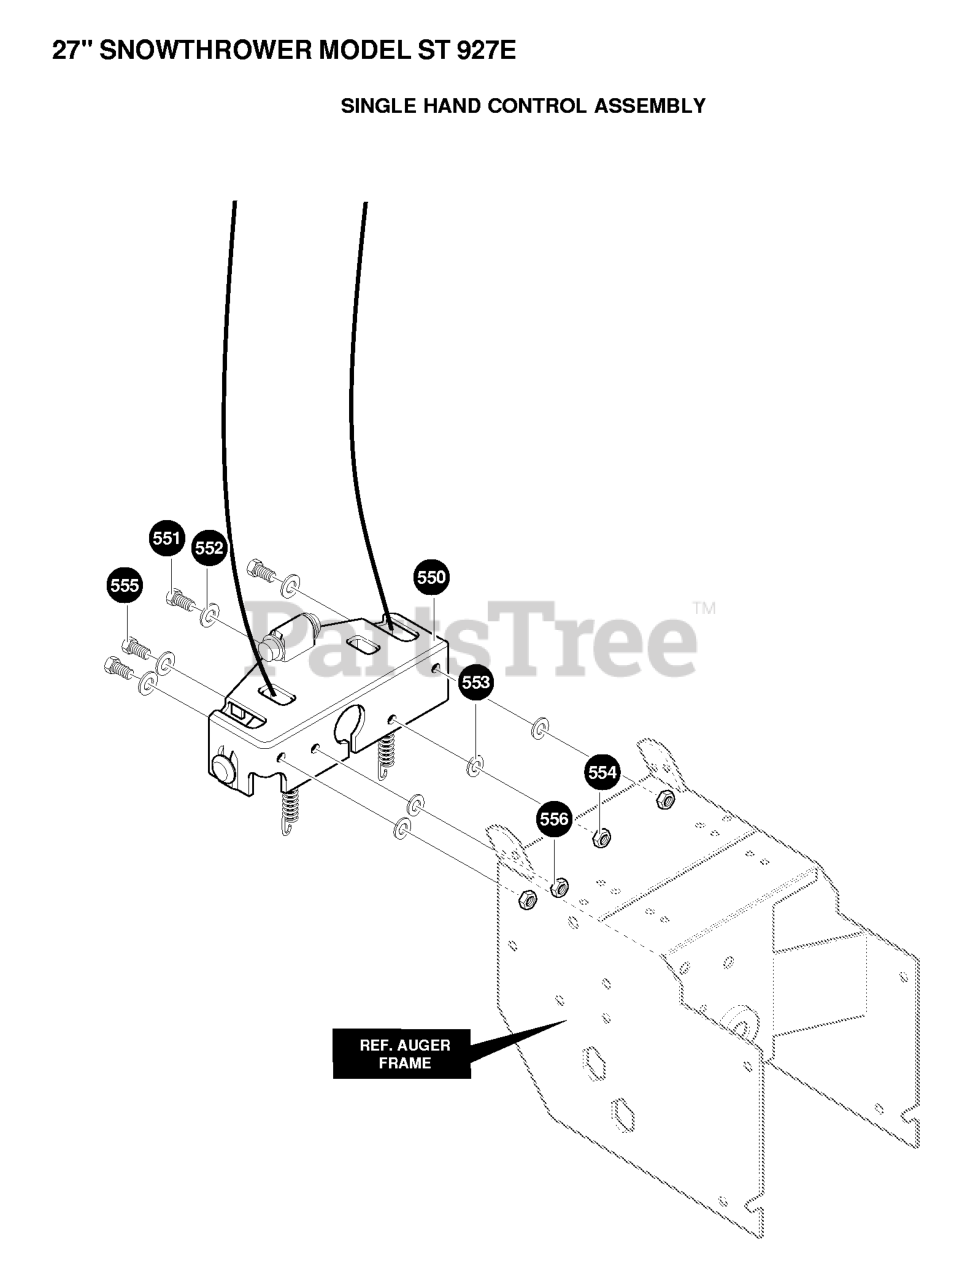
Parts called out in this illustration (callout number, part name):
550	CONTROL, ASSY SINGLE HAND
551	SCREW, 5/16-18X .75 HHC
552	WASHER, FLAT .344X .69X.
553	WASHER, HVSPTLK .328X.60X
554	NUT, 5/16-18 REGHEX
556	NUT,5/16-24
